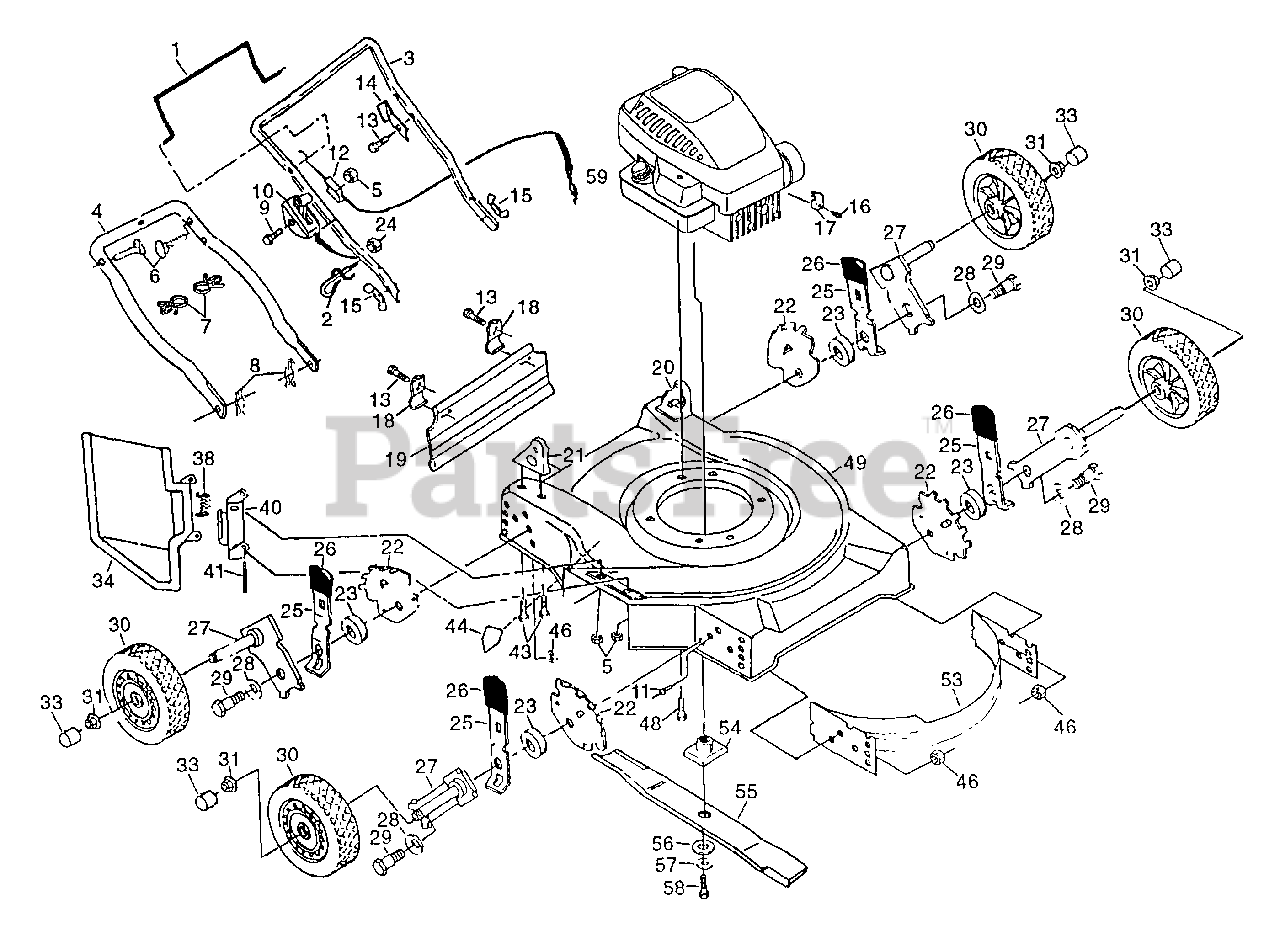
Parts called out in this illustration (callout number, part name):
1	Control Bar
2	Rope Guide (AYP part number)
3	Upper Handle (AYP part number)
4	Lower Handle
5	Locknut
6	Handle Bolt 5/16-18 x 1-3/4 (AYP part number)
7	Cable Clip
8	Hairpin Cotter
9	Hex Washer Head Screw 1/4-20 x 2-1/8
10	Throttle Control
11	Pop Rivet
12	Engine Zone Control Cable
13	Hex Washer Head Screw #10-24 x 1/2
14	Up-Stop Bracket
15	Wing Nut
16	Screw #10 x 5/8
17	Cable Clamp (AYP part number)
18	Skirt Bracket (AYP part number)
19	Rear Deflector (AYP part number)
20	Handle Bracket Assembly (Left) (AYP part number)
21	Handle Bracket Assembly (Right) (AYP part number)
22	Wheel Adjusting Bracket
23	Spacer
24	Keps Locknut 1/4-20
25	Selector Spring
26	Selector Knob
27	Axle Arm Assembly
28	Belleville Washer
29	Shoulder Bolt
30	Wheel & Tire Assembly
31	Flanged Locknut
33	Hubcap
34	Discharge Guard
38	Torsion Spring
40	Housing Bracket Assembly
41	Hinge Rod
43	Screw 5/16-18 x 3/4
44	Danger Decal (AYP part number)
46	Locknut 3/8-16 (AYP part number)
48	Hex Head Thread Rolling Screw 3/8-16 x 1
49	Mower Housing (AYP part number)
54	Blade Adapter
55	Blade 22"
56	Hardened Washer
57	Helical Lockwasher 3/8 (AYP part number)
58	Hex Head Screw 3/8-24 x 1-3/8 (Grd. 8)
59	Engine - Briggs & Stratton
